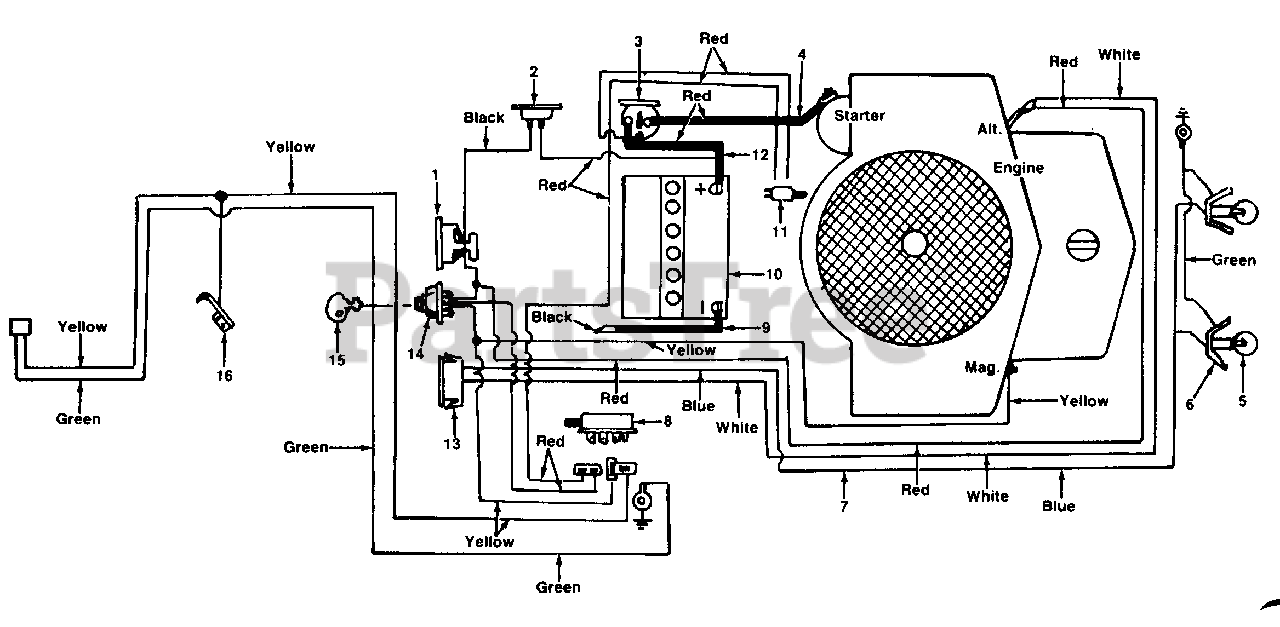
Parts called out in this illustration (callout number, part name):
1	Ammeter
2	Circuit Breaker
3	Solenoid
4	Wire
5	Bulb
6	Socket
7	Wire Harness
8	Safety Switch
9	6 Ga. Black Wire
10	Battery 12V
11	Safety Switch
13	Light Switch
14	Ignition Switch
15	Ignition Key
16	Spring Switch
